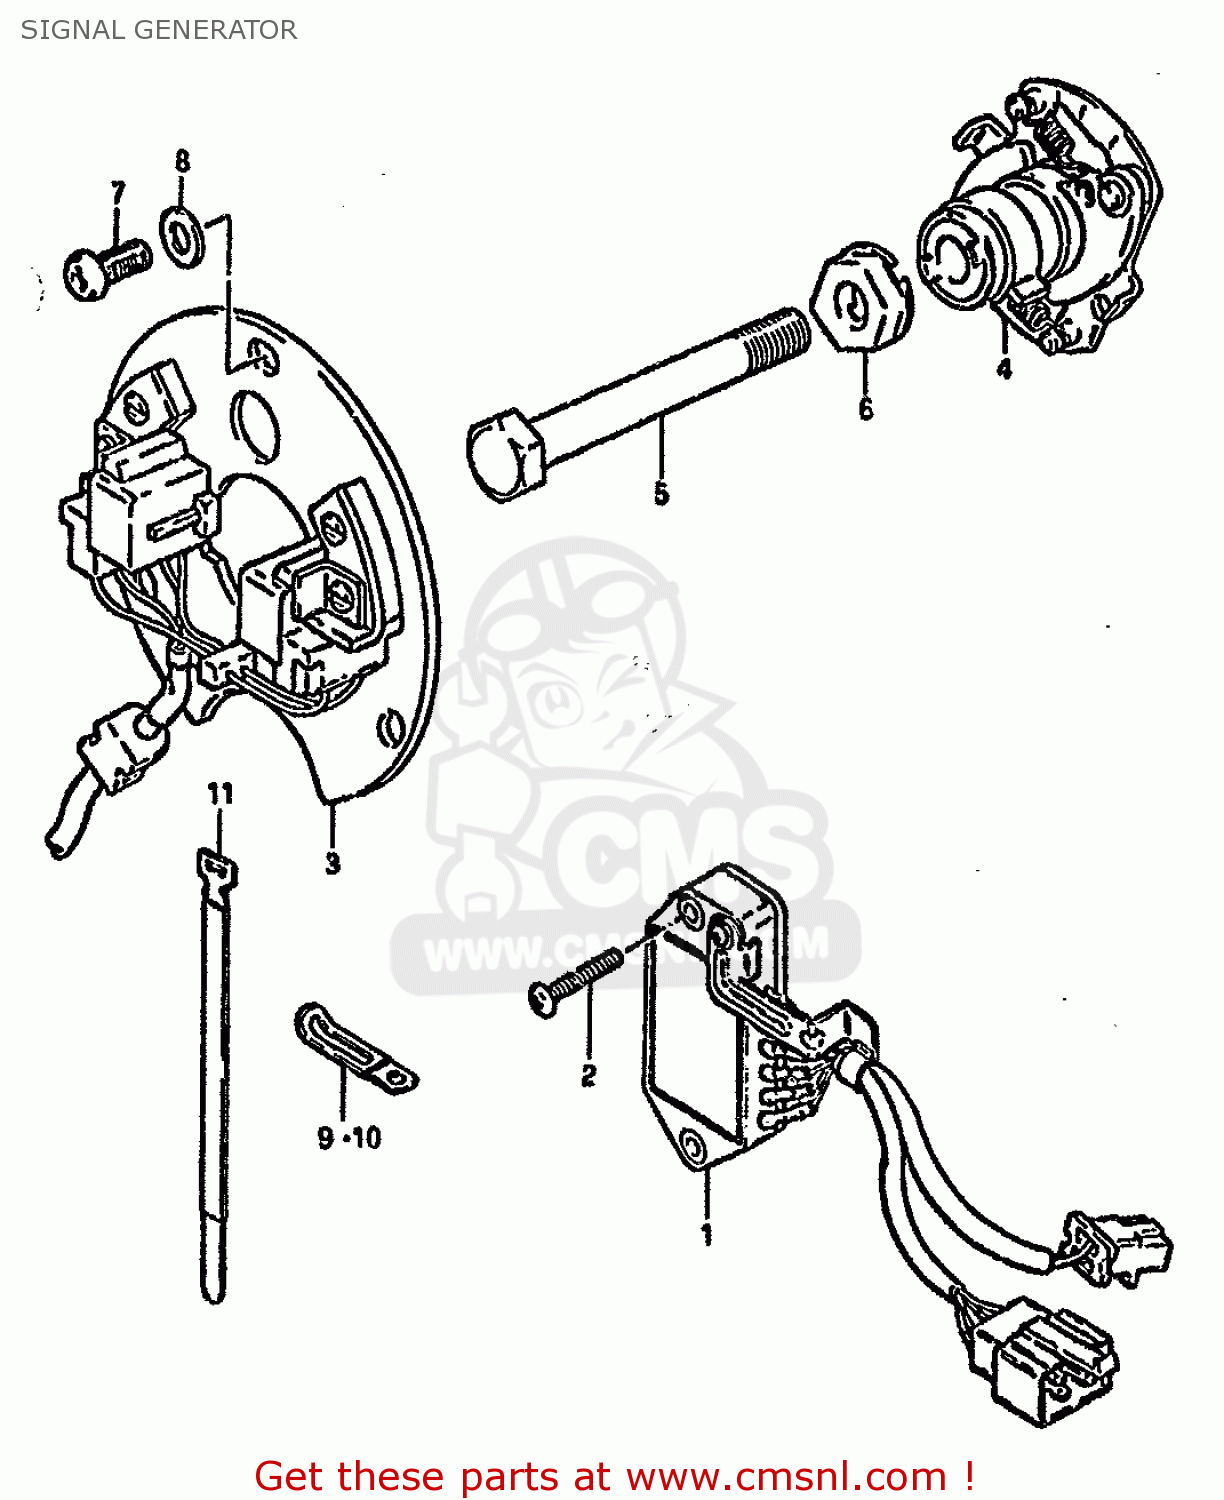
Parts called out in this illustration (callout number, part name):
1	IGNITER UNIT
2	SCREW
3	SIGNAL GENERATOR ASSEMBLY
4	GOVERNOR ASSEMBLY
5	BOLT
6	WASHER
7	SCREW(5X12)
8	WASHER
9	CLAMP L:35
10	CLAMP
11	CLAMP
